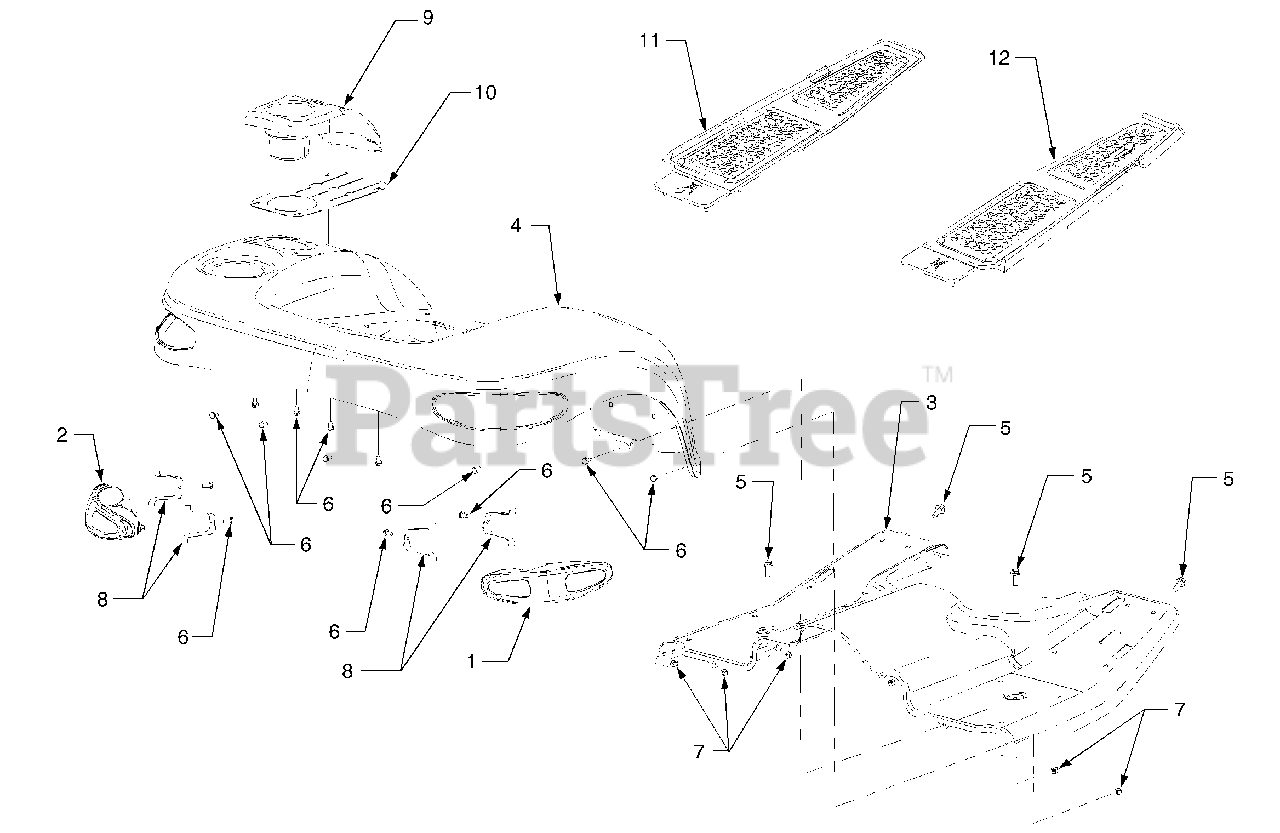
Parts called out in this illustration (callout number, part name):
1	Light Assembly, Rear RH
2	Light Assembly, Rear LH
3	Running Board
4	Fender
5	Screw, Hex Wash. Hd. Tapp 5/16-18 x 1.
6	Screw, Hex Cap, 1/4-20 x .5 GR5
7	Nut, Hex Lock, 1/4-20
8	Clip, Tail Light
9	Cover, Lift Lever
10	Flap, Lift Lever
11	Pad. Floor LH
12	Pad. Floor RH
